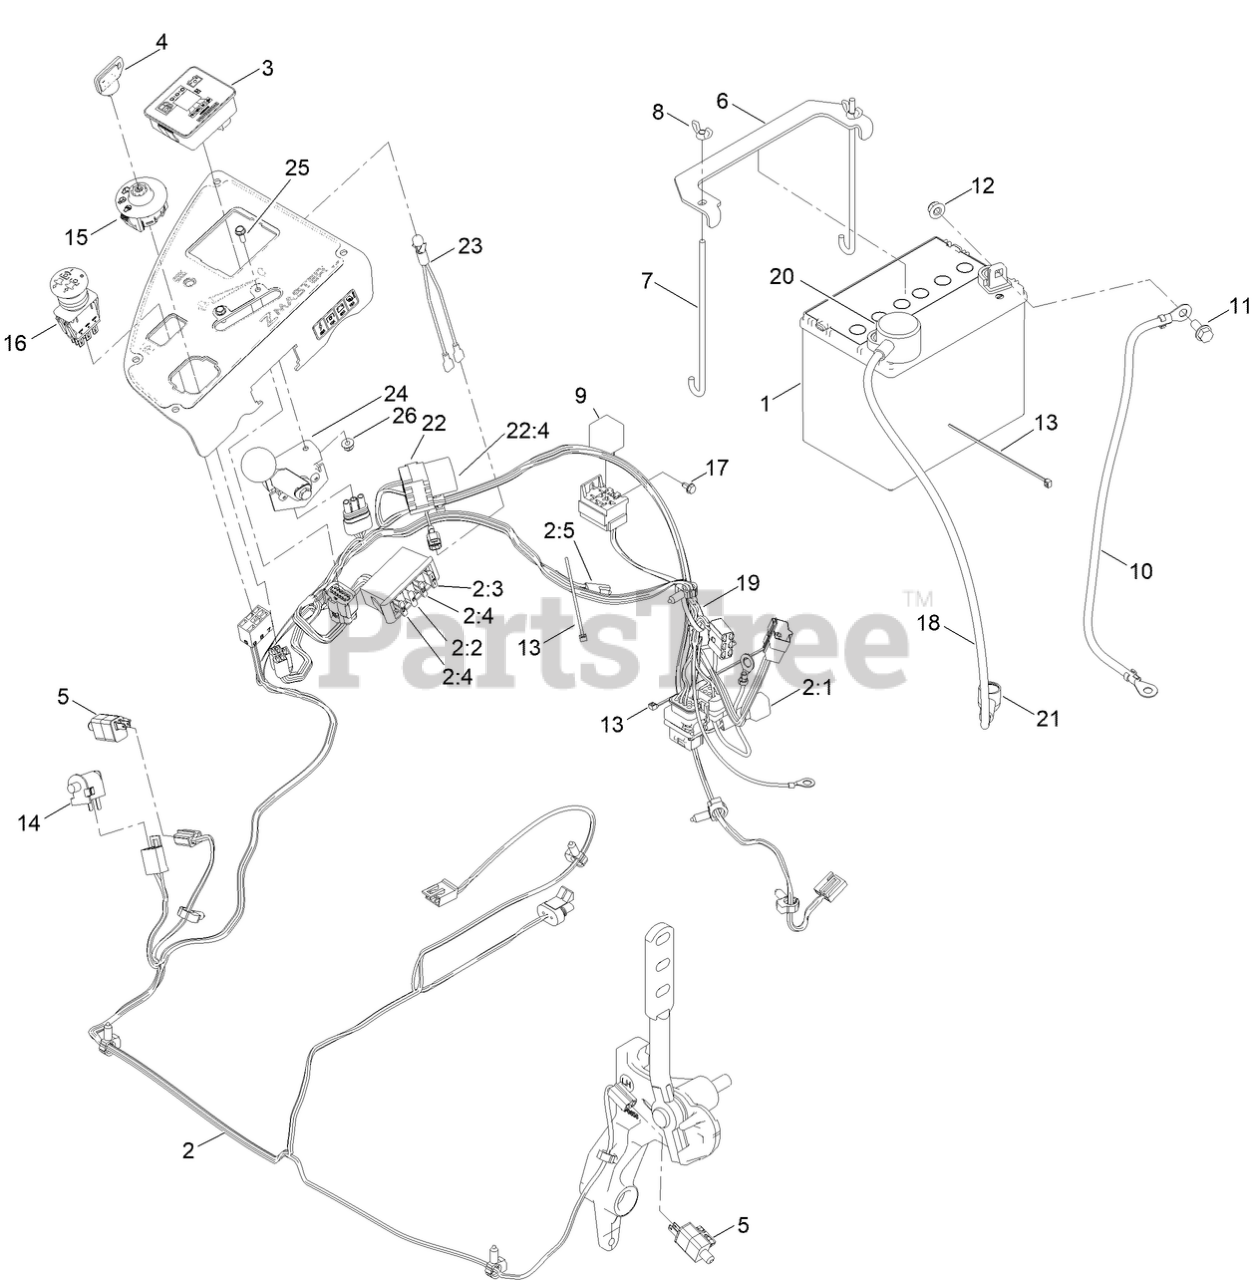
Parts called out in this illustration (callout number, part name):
1	BATTERY-DRY
2	HARNESS-WIRE, MAIN
2:2	FUSE-BLADE, 10 AMP
2:3	FUSE-BLADE, 15 AMP
2:4	FUSE-BLADE, 25 AMP
2:5	CAP-PLUG
3	FUEL/HOUR METER ASM
4	KEYS-IGNITION (SPARE PAIR)
4	KEY-IGNITION
5	SWITCH
6	STRAP-TIE DOWN, BATTERY
7	BOLT-HOLDDOWN
8	WINGNUT
10	CABLE-BATTERY, NEGATIVE
11	SCREW-HHF
12	NUT-HF, NI
13	TIE-CABLE
14	SWITCH-BAIL
15	SWITCH-IGNITION
16	SWITCH, PTO 10A
17	SCREW-HWH
18	CABLE-BATTERY, POSITIVE
19	TIE-CABLE
20	INSULATOR-BATTERY
21	INSULATOR-SOLENOID
22	HARNESS-ADAPTER EFI, ETC
23	INDICATOR-LED, RED
24	THROTTLE CONTROLLER-ETC
25	SCREW-HWH
26	NUT-HF
